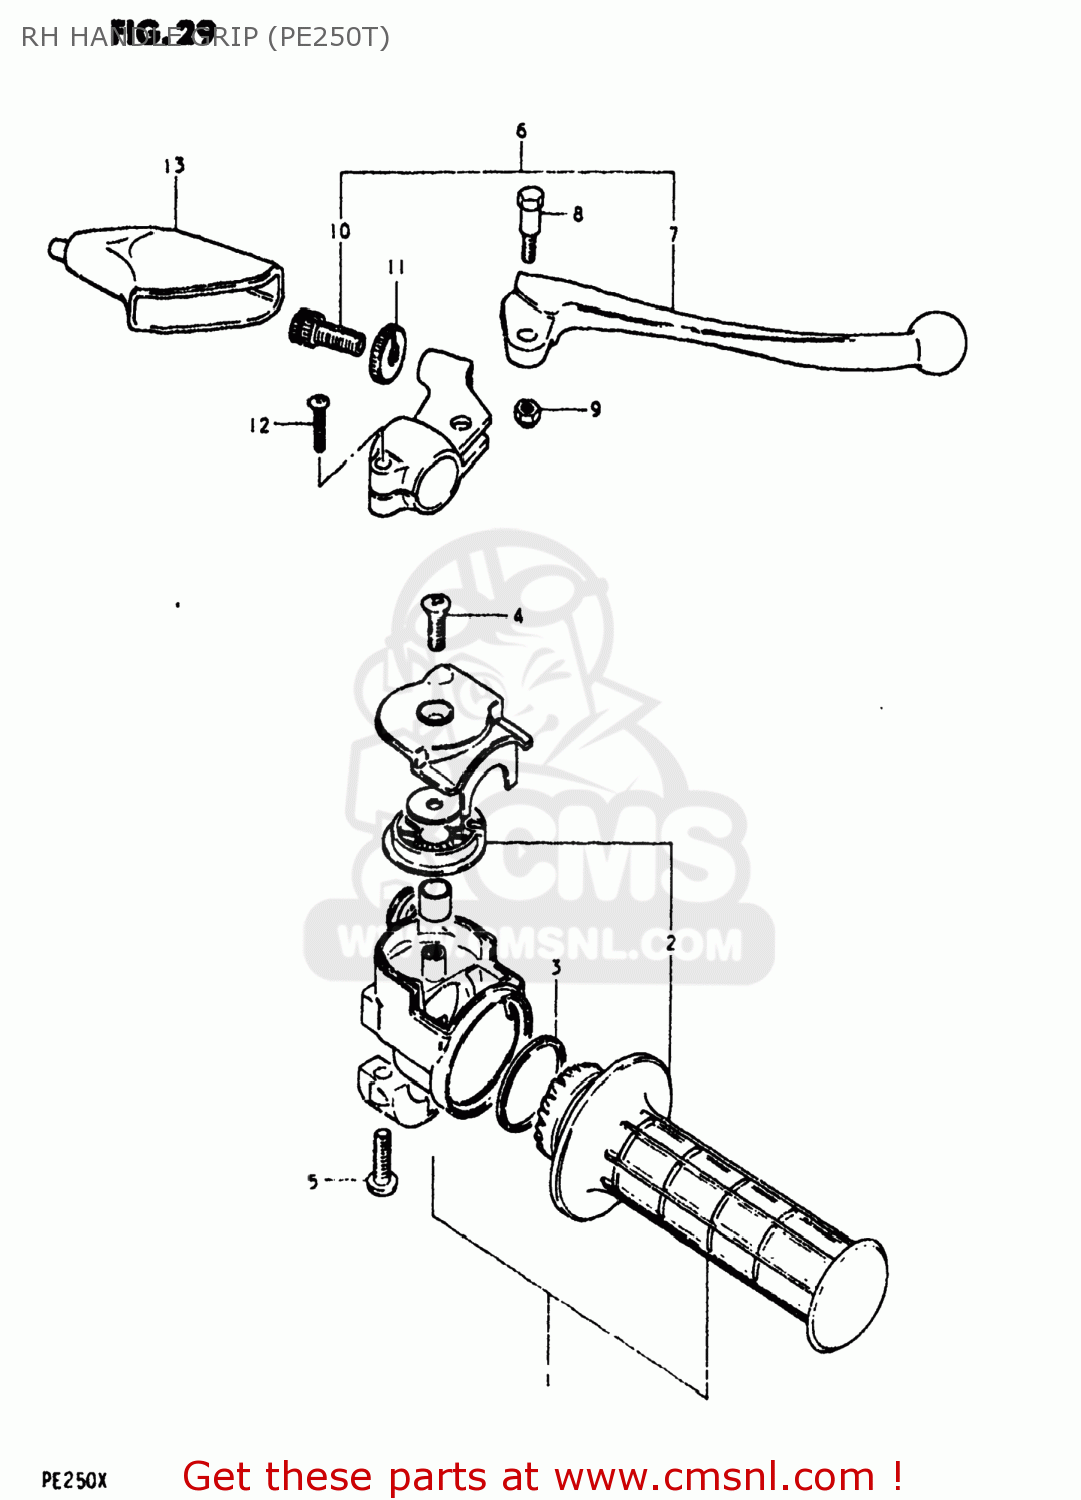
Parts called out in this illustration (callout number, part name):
1	CASE ASSEMBLY,THROTTLE
2	GRIP SET,THROTTLE
3	V-RING,THROTTLE GRIP
4	SCREW
5	SCREW 5X20
6	LEVER ASSY,BRAKE
7	LEVER,BRAKE
8	BOLT,LEVER
9	NUT 6MM
10	ADJUSTER,CABLE
11	NUT,CABLE ADJUSTER
12	SCREW
13	COVER,CLUTCH LEVER
